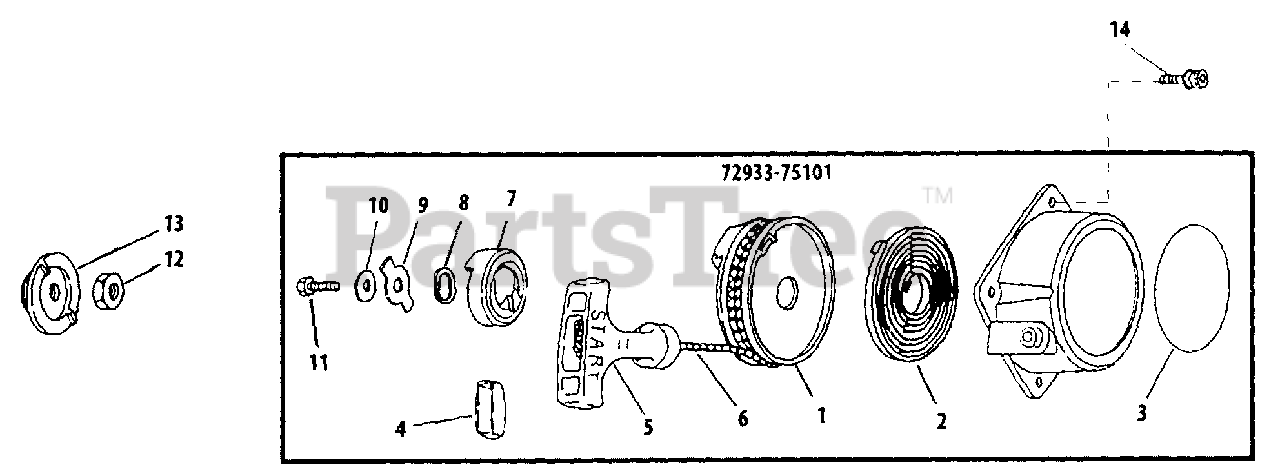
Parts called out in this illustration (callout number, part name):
1	REEL, ROPE
2	SPRING, REWIND
3	LABEL - IDENTIFICATION
4	RETAINER, ROPE
5	HANDLE
6	ROPE, STARTER
7	PAWL, STARTER
8	WASHER - SPRING
9	RETAINER
10	WASHER - 5
11	SCREW - 5
12	NUT - 8
13	PAWL
14	SCREW - 4X12
72933-75101	STARTER ASSY
